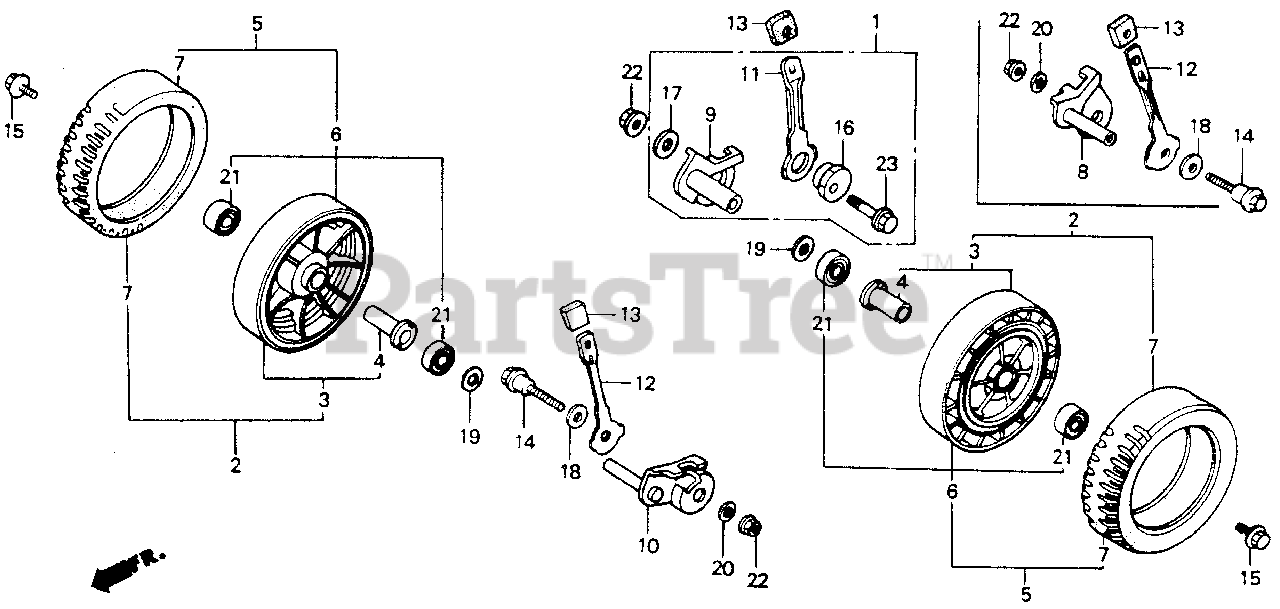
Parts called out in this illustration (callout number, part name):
1	ADJUSTING KIT, WHEEL
5	WHEEL (8") (NH31)
6	WHEEL (8") (NH31)
7	TIRE (8 INCH)
8	ARM A, WHEEL ADJUSTING (NOT AVAILABLE)
9	ADJUSTING KIT, WHEEL
10	ARM B, WHEEL ADJUSTING
11	PLATE, FR. ADJUSTING (PART NEWS #006)
12	PLATE, FR. ADJUSTER
13	GRIP, ADJUSTER
14	BOLT, ADJUSTING CENTER
15	BOLT, WHEEL
16	ADJUSTING KIT, WHEEL
18	WASHER (10MM)
19	WASHER, WHEEL
20	WASHER (8MM)
20	WASHER A, HANDLE HOLDER SETTING
21	BEARING, RADIAL BALL
22	NUT, FLANGE (8MM)
23	BOLT, FLANGE (8X45)
